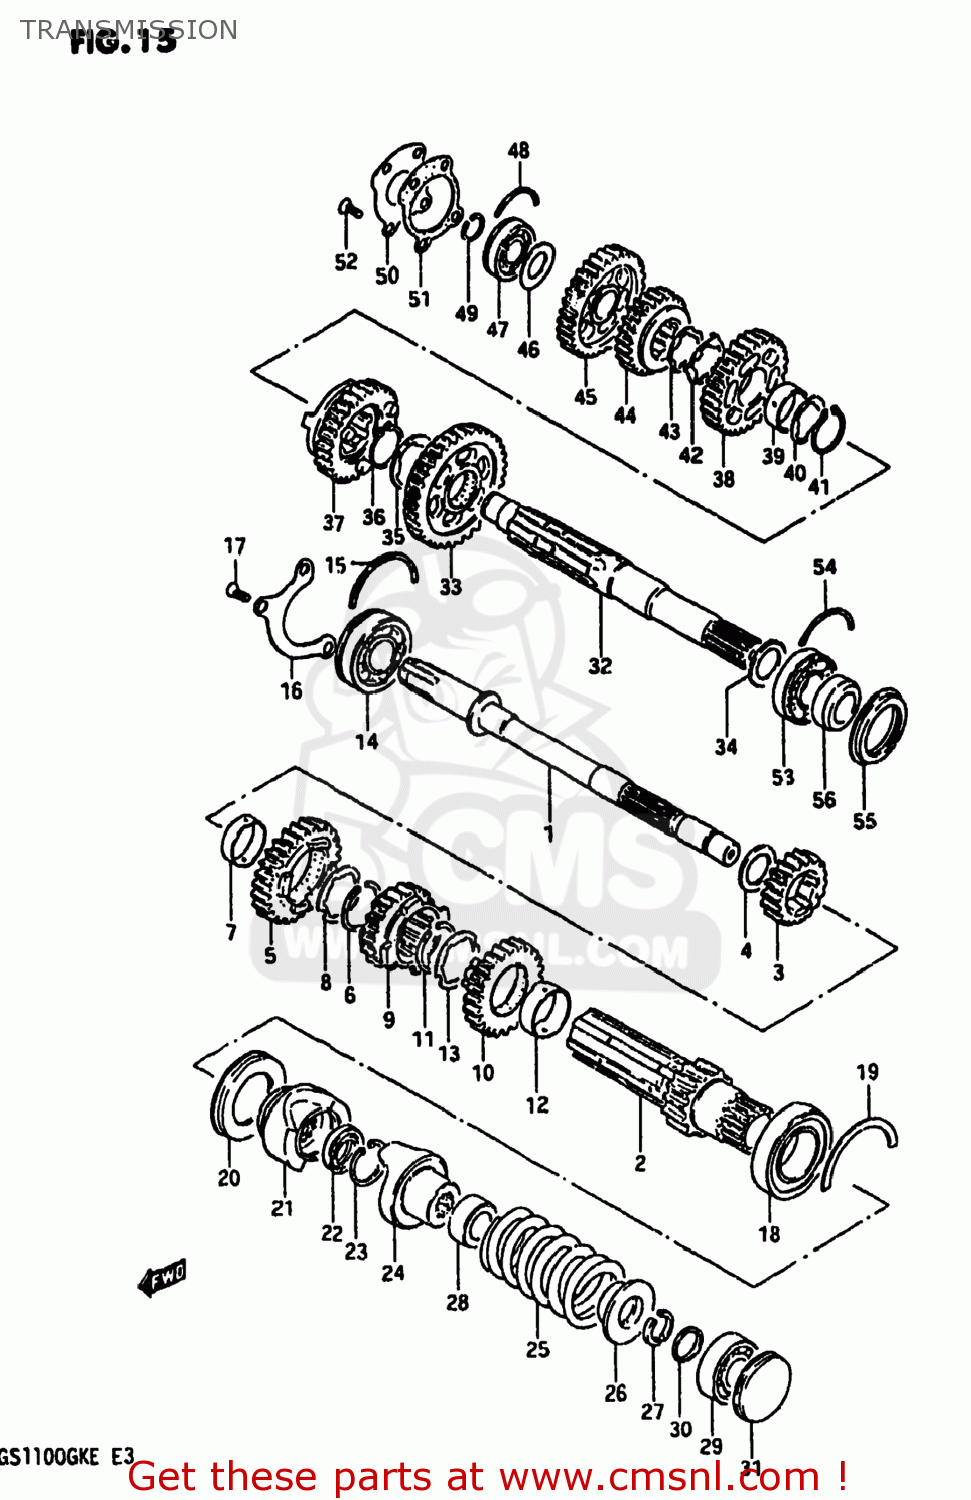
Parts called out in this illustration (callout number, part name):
1	SHAFT,INNER COUNTER
2	SHAFT,OUTER COUNTER
3	GEAR,SECOND DRIVE
4	WASHER (21X35X2)
5	GEAR,5TH DRIVE(NT:26)
6	RING,SNAP
7	SPACER,DRIVE GEAR
8	LOCK WASHER,5TH DR GEAR SPACER
9	GEAR,THIRD DRIVE
10	GEAR,FOURTH DRIVE
11	RING,SNAP
12	SPACER,DRIVE GEAR
13	LOCK WASHER,5TH DR GEAR SPACER
14	BEARING(25X62X17)
15	C-RING
16	RETAINER,CNTR SHAFT BEARING
17	SCREW
18	BALL BEARING 32X58X13
19	C-RING
20	SEAL,OIL(40X58X7)
21	DOG,OUTPUT CAM
22	SEAL,OIL(20.6X31X6)
23	CIRCLIP
24	DOG,INPUT CAM
25	SPRING
26	STOPPER,CAM DOG SLIDING
27	STOPPER,CAM DOG
28	GUIDE,CAM DOG SPRING
29	BEARING
30	SPACER (17X21X3.5)
31	PLUG
32	SHAFT,DRIVE
33	GEAR,FIRST DRIVEN
34	WASHER, LH
35	WASHER,LOCK
36	CIRCLIP
37	GEAR,FOURTH DRIVEN
38	GEAR,THIRD DRIVEN
39	BUSH,3RD DRIVEN GEAR
40	WASHER,LOCK
41	CIRCLIP
42	WASHER
43	WASHER,LOCK
44	GEAR,FIFTH DRIVEN
45	GEAR,SECOND DRIVEN
46	WASHER
47	BEARING(20X47X14)
48	C RING
49	CIRCLIP
50	PLATE,DRIVESHAFT
51	GASKET,DRIVESHAFT PLATE (MCA)
52	SCREW
53	BEARING
54	C RING
55	SEAL,OIL(35X52X6)
56	SPACER,DRIVESHAFT,LEFT
